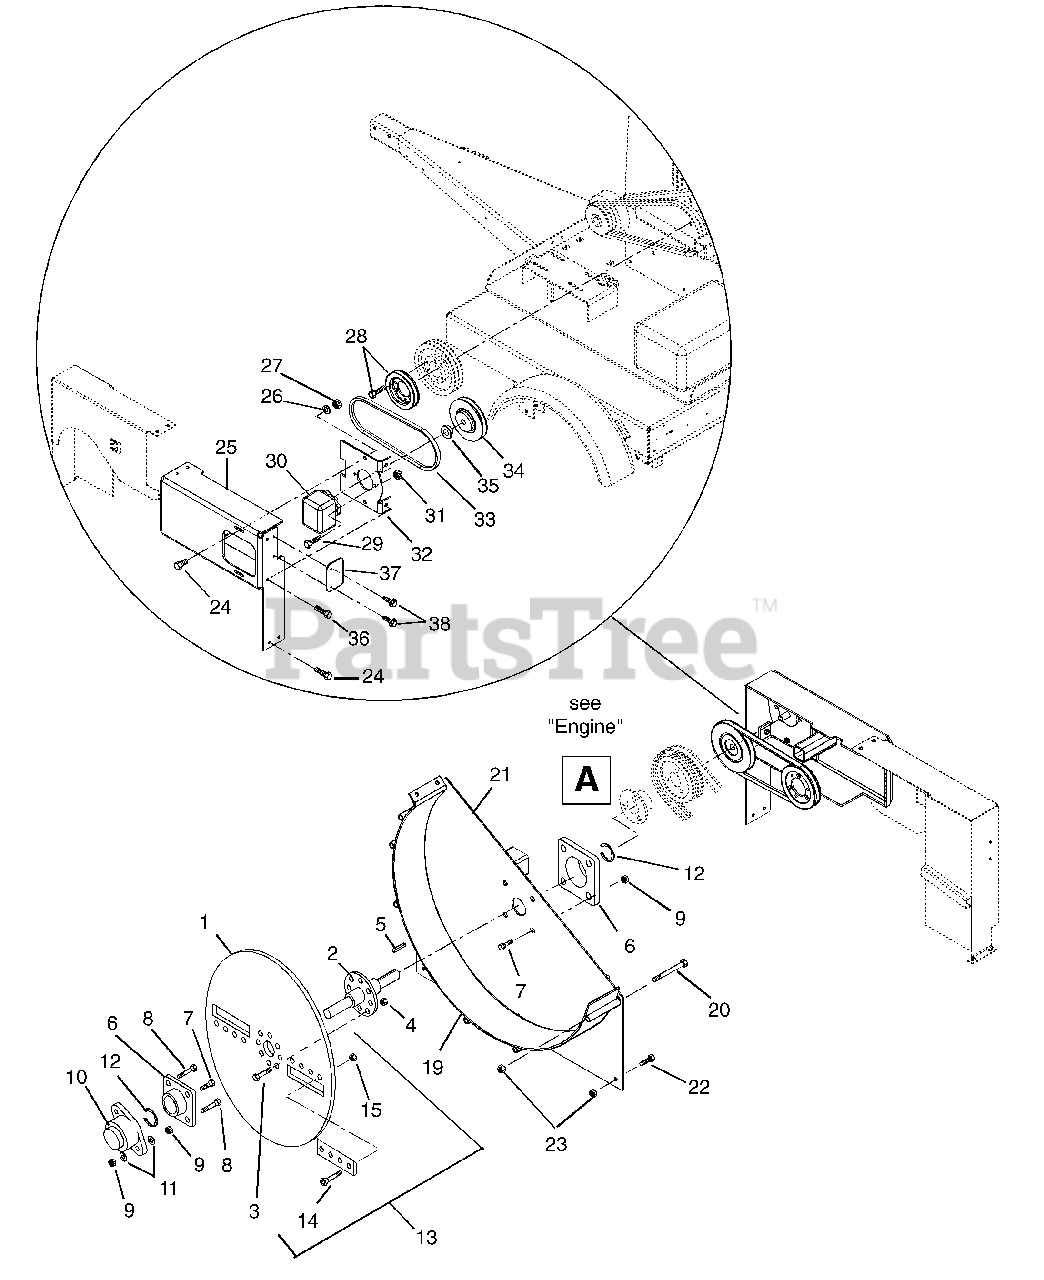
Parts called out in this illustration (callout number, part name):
1	Cutting Wheel
2	Arbor Shaft
3	Bolt-Hex .50-13 x 2.00 Grade 5
4	Nut-Locking-Center .50-13
5	Key-Straight .38 x 2.75 x .38
6	4 Hole Flange Bearing
7	Bolt-Lug .50-20 x 1.50
8	Wheel Lug Bolt 1/2-20 x 2.50
9	Nut-Locking-Center .50-20
10	Bearing Cover
11	Washer-Flat-Steel .531 x 1.06 x .095
12	Ring-Retaining-External 1.500 x .109
13	Chipper Knife Set
14	Bolt-Flat Socket Head .50-13 x 1.75 Grade 8
15	Nut-Locking .50-13 Grade C555
16	Weldment, Pump Adjustment Bracket
17	Bolt-Hex .44-14 x 1.50 Grade 5
18	Nut-Locking-Center .44-14
19	Wrapper Weldment-Flywheel Housing
20	Bolt-Hex .38-16 x 5.75 Grade 5
21	Plate Weldment-Flywheel Housing
22	Bolt-Hex .38-16 x .75 Grade 5
23	Nut-Locking-Center .38-16
24	Bolt-Hex .38-16 x .75 Grade 5
25	Weldment,Pump Mount/Cover
26	Washer-Locking .38 x .094
27	Nut-Locking-Center .38-16
28	Sheave, Pump To Flywheel
29	Bolt-Hex .44-14 x 1.50 Grade 5
30	Pump-Hydraulic
31	Nut-Locking-Center .44-14
32	Weldment, Pump Adjustment Bracket
33	Belt, Lower 48" Deck 5L x 43
35	Bushing-Sheave
36	Bolt-Hex .38-16 x 2.25 Grade 5
37	Pulley Guard
38	Screw - Tap .25-20 x .50
